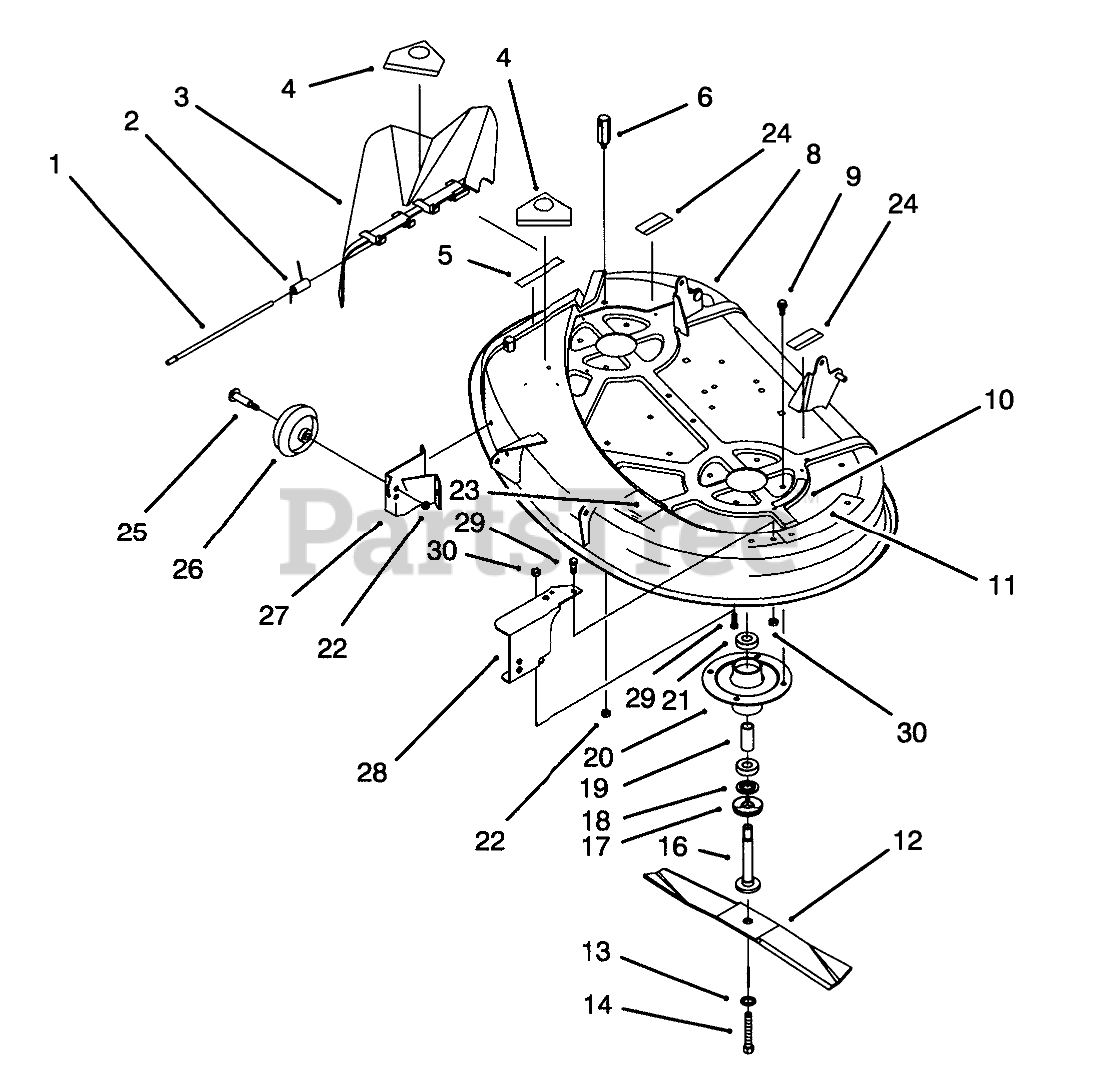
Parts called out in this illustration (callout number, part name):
1	ROD-HINGE DEFLECTOR
2	SPRING
3	Deflector Assembly (Incl. Ref. #4)
4	DECAL-DANGER
5	DECAL-DANGER, DEFLECTOR
6	REAR PIVOT POST (PLTD)
8	Deck-38"
9	SCREW-TAPTITE
10	DECAL-DANGER, SHIELD
11	DECAL-DANGER
12	Blade
13	WASHER-BELLEVILLE
14	SCREW-HH
16	SHAFT-SPINDLE
17	SHIELD-BEARING
18	SPACER
19	SPACER
20	HOUSING-SPINDLE
21	BEARING-BALL
22	NUT-LOCK, NI
23	Decal-Routing
24	DECAL-WARNING
25	SCREW-SHOULDER, HWH
26	WHEEL-GAGE
27	Bracket-R.H.
28	LH WHEEL DECK BRKT
29	SCREW-HH
30	NUT-LOCK, NI
